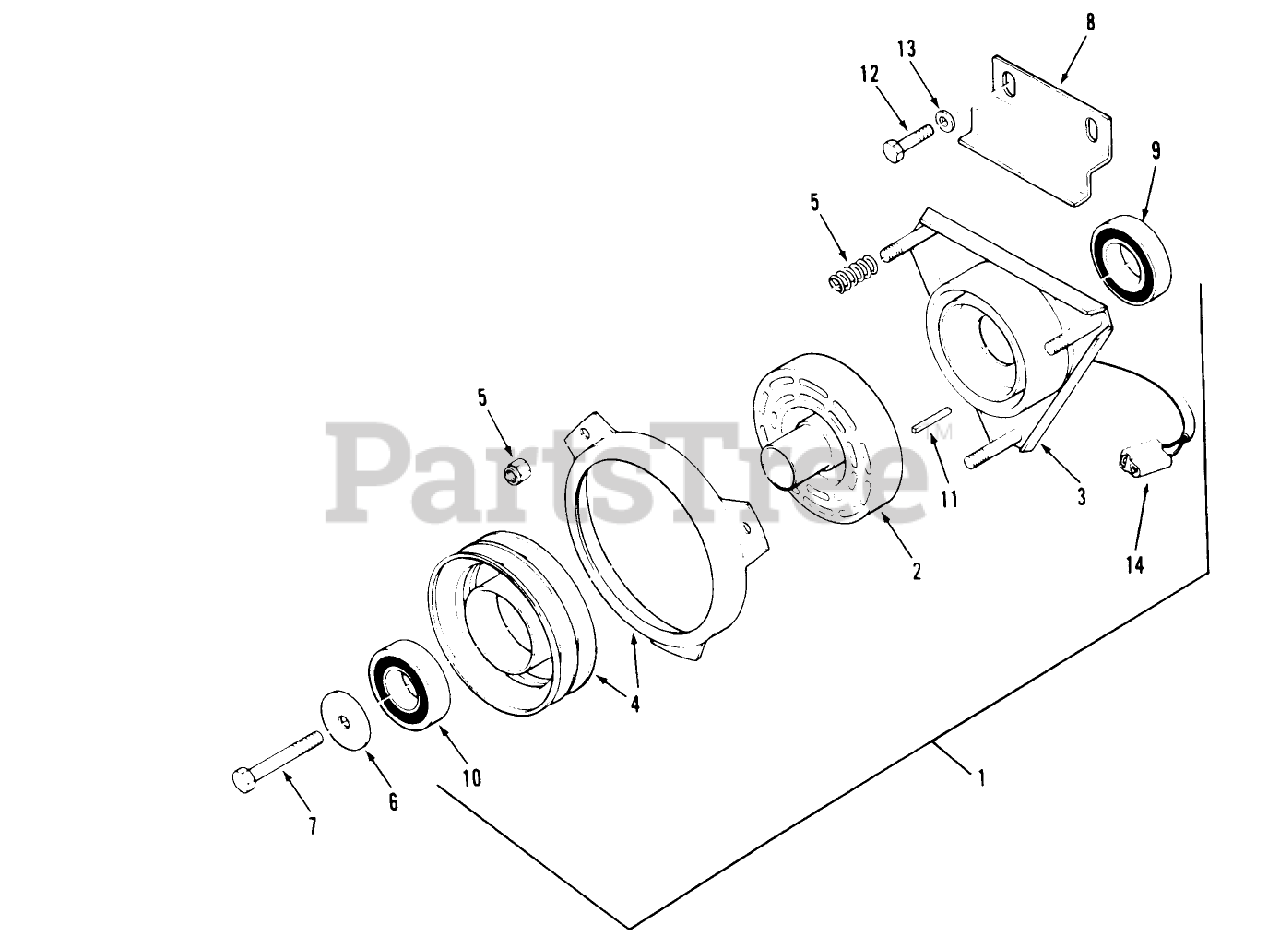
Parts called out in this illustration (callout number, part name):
2	ASM-ROTOR & ARMATURE
3	FIELD-ASS'Y
5	ACCESS SPRING & NUT
6	RETAINER-BEARING
7	SCREW-HH
8	BRACKET-CLUTCH *B
9	BEARING-FIELD ASS'Y
10	BEARING-ELEC CLUTCH
11	KEY-SQUARE
12	SCREW-HH
13	WASHER-FLAT
14	CONNECTOR BODY *B
